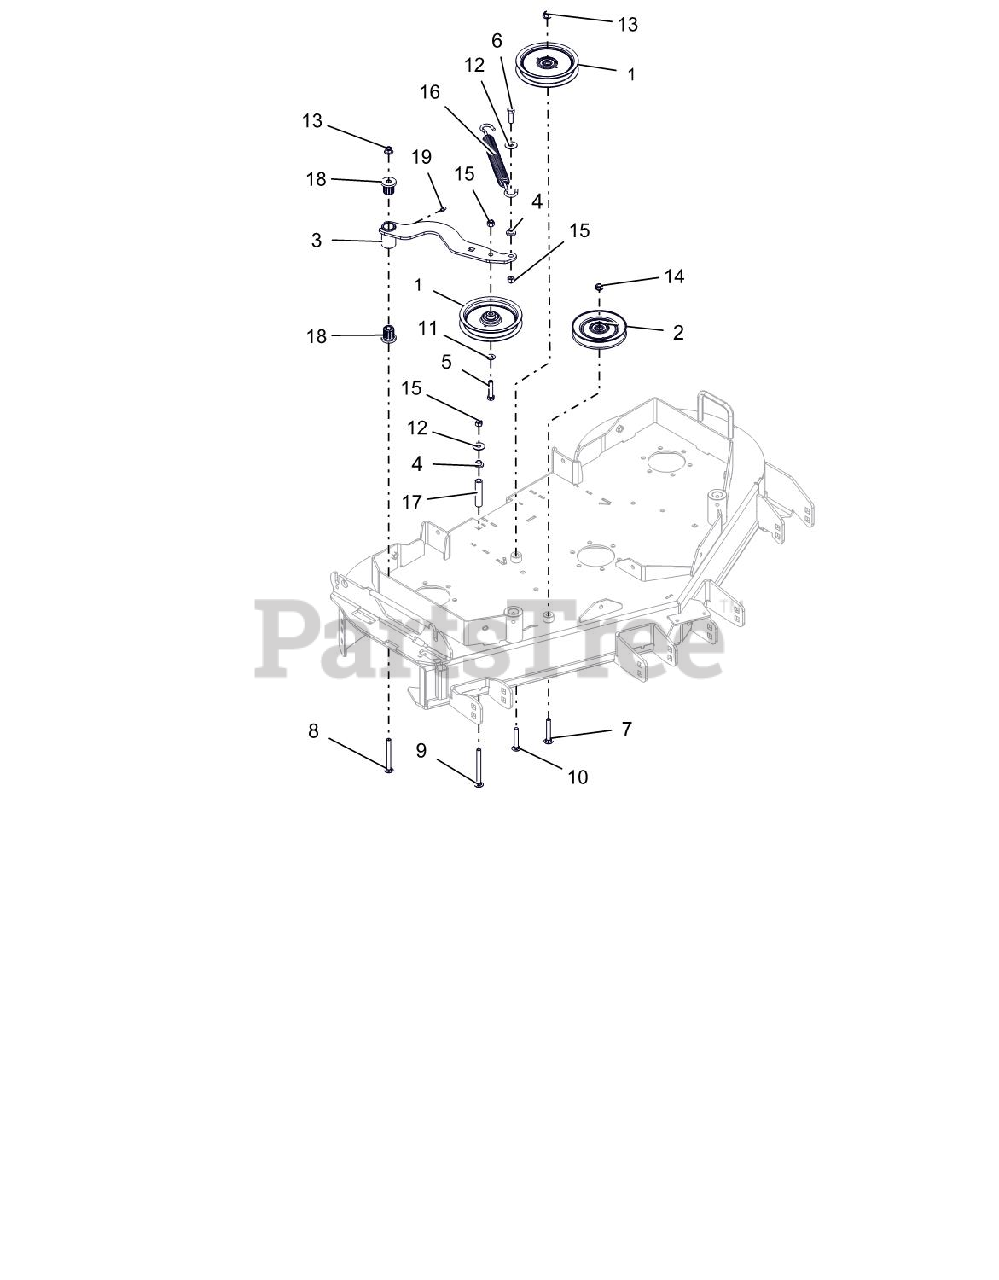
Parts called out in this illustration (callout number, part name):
1	IDLER, FLAT-5.00X.75
2	IDLER, V-5.00
3	WLDMT, IDLER ARM
4	BSHG-FLG .385X.500X.875X.406
5	BLT, HEX .38-16X1.75 G5ZC120
6	BLT, HEX .38-16X1.25 G5 ZCC
7	BLT,RHSN .38-16X2.50 G5 ZC120
8	BLT,RHSSN .38-16X3.50 G5 ZCC
9	BLT,RHSSN .38-16X4.00 G5 ZCC
10	BLT,RHSN .38-16X2.25 G5 ZCC
11	WSHR,FL-STL.406X.812X.065ZC120
12	WSHR-FL-STL .375X1.125X.065 ZC
13	NUT,LK-NYL-FLG .38-16 G5ZC120
14	NUT, SPNLK-FLG .38-16 G5ZC120
15	NUT,NYL .38-16 G5 ZCC
16	SPRING, EXTENSION
17	TUBE, SPACER
18	BRG, FLG M10XM25XM27 FLUTED
19	FTG-LUBE .25-28X.256 SST
